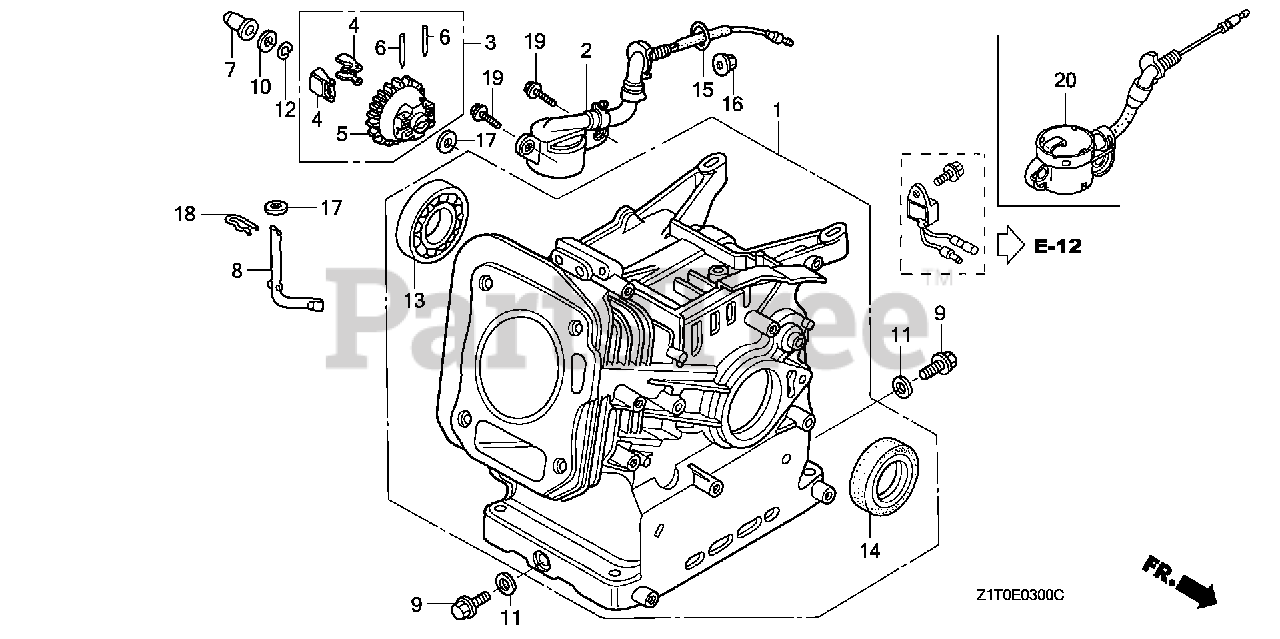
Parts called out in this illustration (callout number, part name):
1	CYLINDER ASSY. (OIL ALERT)
2	SWITCH ASSY., OIL LEVEL
3	GOVERNOR ASSY.
4	WEIGHT, GOVERNOR
5	HOLDER, GOVERNOR WEIGHT
6	PIN, GOVERNOR WEIGHT
7	SLIDER, GOVERNOR
8	SHAFT, GOVERNOR ARM
9	BOLT, DRAIN PLUG
10	WASHER, THRUST (6MM)
11	WASHER, DRAIN PLUG (10.2MM)
12	CLIP, GOVERNOR HOLDER
13	BEARING, RADIAL BALL (6205TMB) (NTN)
14	OIL SEAL (25X41X6)
15	O-RING (14MM) (ARAI)
15	O-RING (14MM) (NOK)
16	NUT, FLANGE (10MM)
17	WASHER, PLAIN (6MM)
18	PIN, LOCK (8MM)
19	BOLT, FLANGE (6X12)
